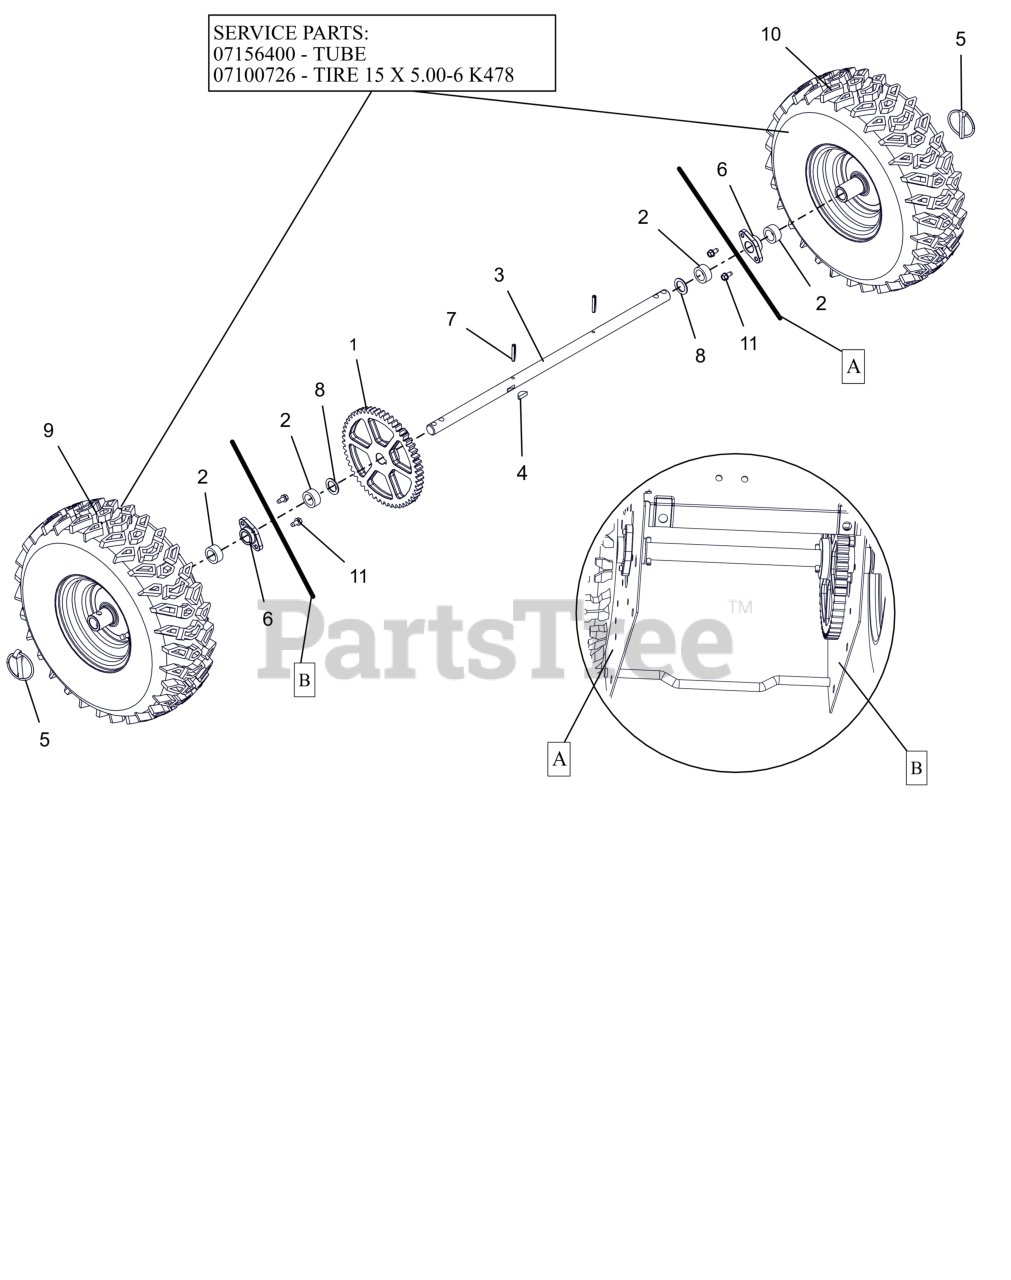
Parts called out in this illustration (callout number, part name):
1	SPUR GEAR, 54T .75ID X 6.75PD
2	BSHG-SLV .766 X 1.125 X .500
3	AXLE, COMPACT
4	KEY-WDRF .25X.750X.313 SAE91
5	PIN-LOK .31X1.75
6	BSHG .75X1.125X.65
7	PIN-ROLL .188X1.25
8	WSHR, FLT .754X1.125X.062 ZCC
9	TIRE/WHEEL,RH 15X5.00-6 PIN T2
10	TIRE/WHEEL,LH 15X5.00-6 PIN T2
10	TUBE 15 X 5.00-6
10	TIRE, 15X5.00-6 K478
11	SCR-TAP .25-20X.50 HWH ZCC
